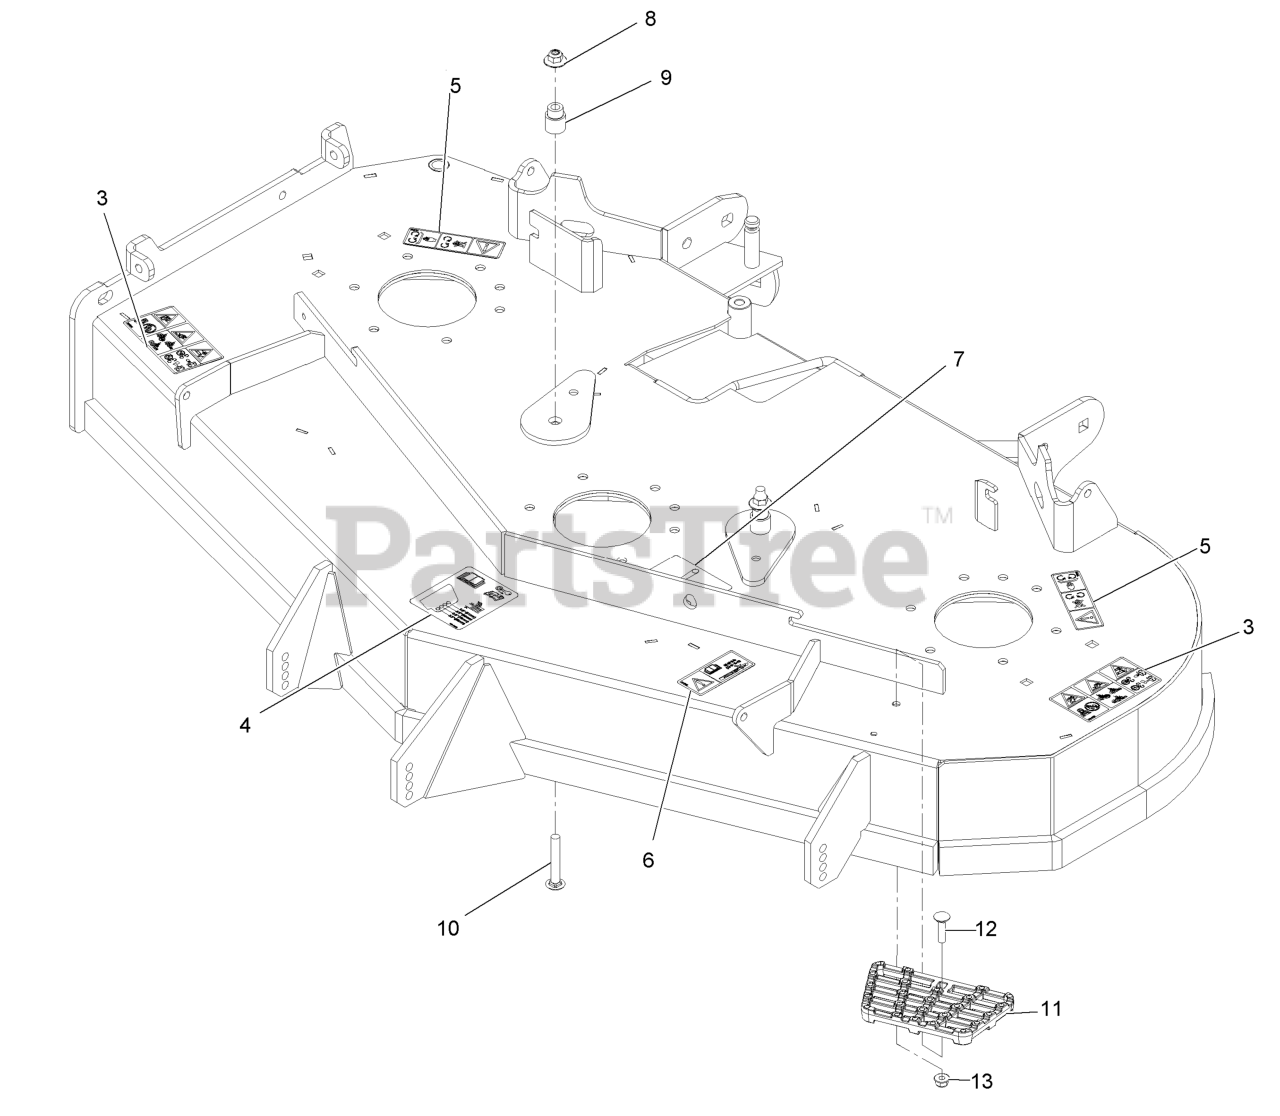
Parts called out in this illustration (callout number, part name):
3	DECAL-DANGER THROWN OBJECTS
4	DECAL-ROLLER, ANTI-SCALP
5	DECAL-COVER, MISSING
6	DECAL-BOLT TORQUE
7	DECAL-BELT ROUTING
8	Nut-Nyloc 3/8-16 Flg
9	BUSHING-IDLER
10	SCREW-CARR
11	STEP-DECK
12	Bolt-Carriage 5/16-18 X 1 1/4
13	NUT-HF, NI
